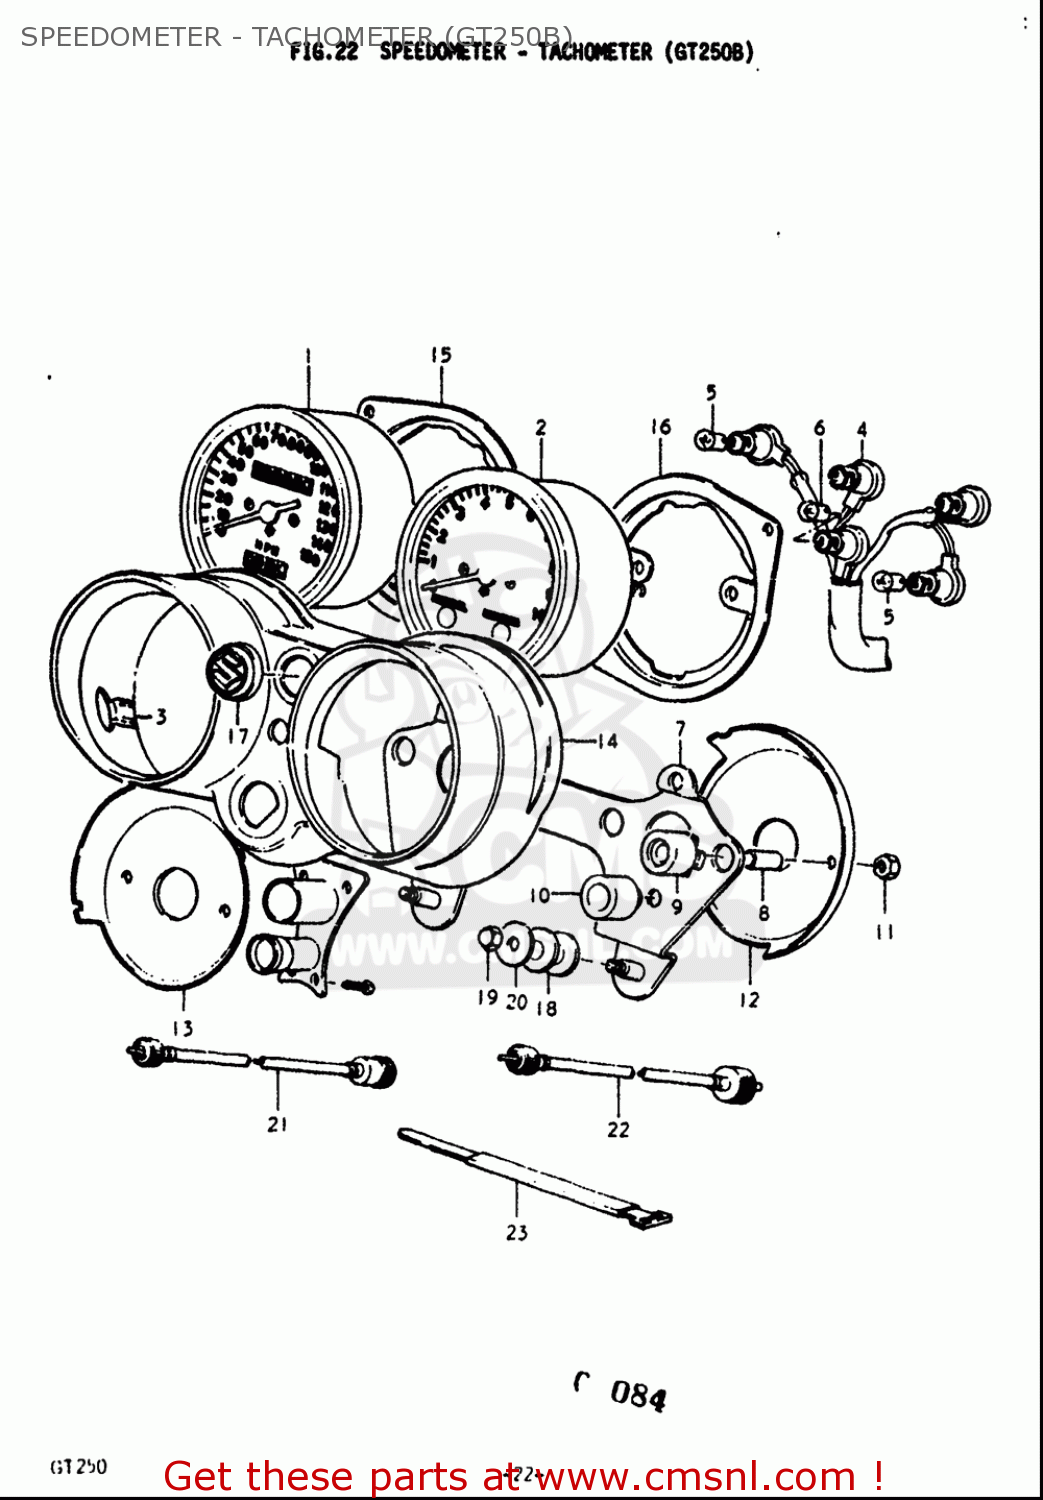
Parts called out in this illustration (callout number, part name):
5	BULB(12V3.4W,STANLEY,A72A)
6	BULB(12V1.7W,A71A)
9	CUSHION,METER NO.1
10	CUSHION,METER
11	NUT
15	BRACKET,SPEEDOMETER
16	PLATE,TACHOMETER
17	CAP,SPEED WARNER LAMP HOLE
18	CUSHION
19	NUT
20	WASHER(6.5X18X1.6)
21	CABLE ASSY,SPEEDOMETER
22	CABLE ASSY,TACHOMETER
23	CLAMP
